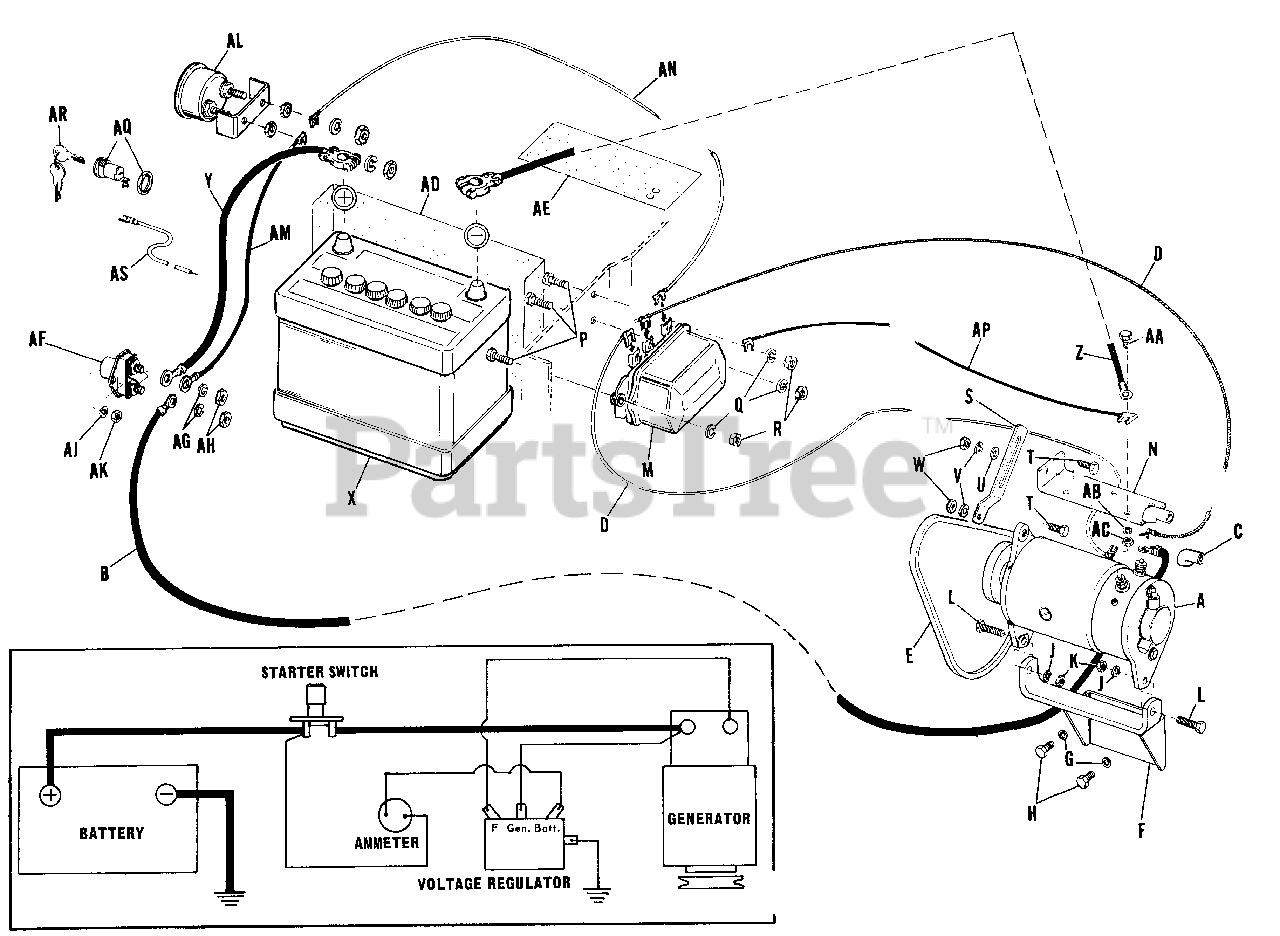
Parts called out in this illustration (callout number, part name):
A	Motor-Generator
B	Cable, Generator, Start
C	Terminal Cover
D	Wire, Reg. Gen.
F	Support Assembly
G	Lock Washer, 5/16"
H	Hex Capscrew, 5/16"-18 x 3/4" lg.
J	Lock Washer, 5/16 "
K	Hex Nut, Full, 5/16"-18
L	Hex Capscrew, 5/16"-18 x 1-1/4"
M	Voltage Regulator
P	Hex Capscrew, 1/4"-20 x 3/4" lg.
Q	Lock Washer, 1/4"
R	Hex Nut, Full, 1/4"-20
S	Belt Tightener
T	Hex Capscrew, 5/16"-18 x 3/4" lg.
U	Plain Washer, 5/16"
V	Lock Washer, 5/16"
W	Hex Nut, Full, 5/16"-18
Y	Cable (Battery to Starter)
Z	Cable (Battery to Ground)
AA	Hex Capscrew, 1/4"-20 x 5/8" lg.
AB	Lock Washer, 1/4"
AC	Hex Nut, Full, 1/4"-20
AD	Battery Insulation
AE	Fuel Tank Insulation
AF	Starter Switch
AG	Lock Washer, 3/8"
AH	Hex Nut, Full
AJ	Lock Washer, 1/4"
AK	Hex Nut, Full, 1/4"-20
AL	Ammeter
AM	Wire (Ammeter to Starter)
AN	Wire (Ammeter to Regulator)
AP	Wire (Ground to Ground)
AQ	Ignition Switch
AS	Wire (Switch to Engine)
